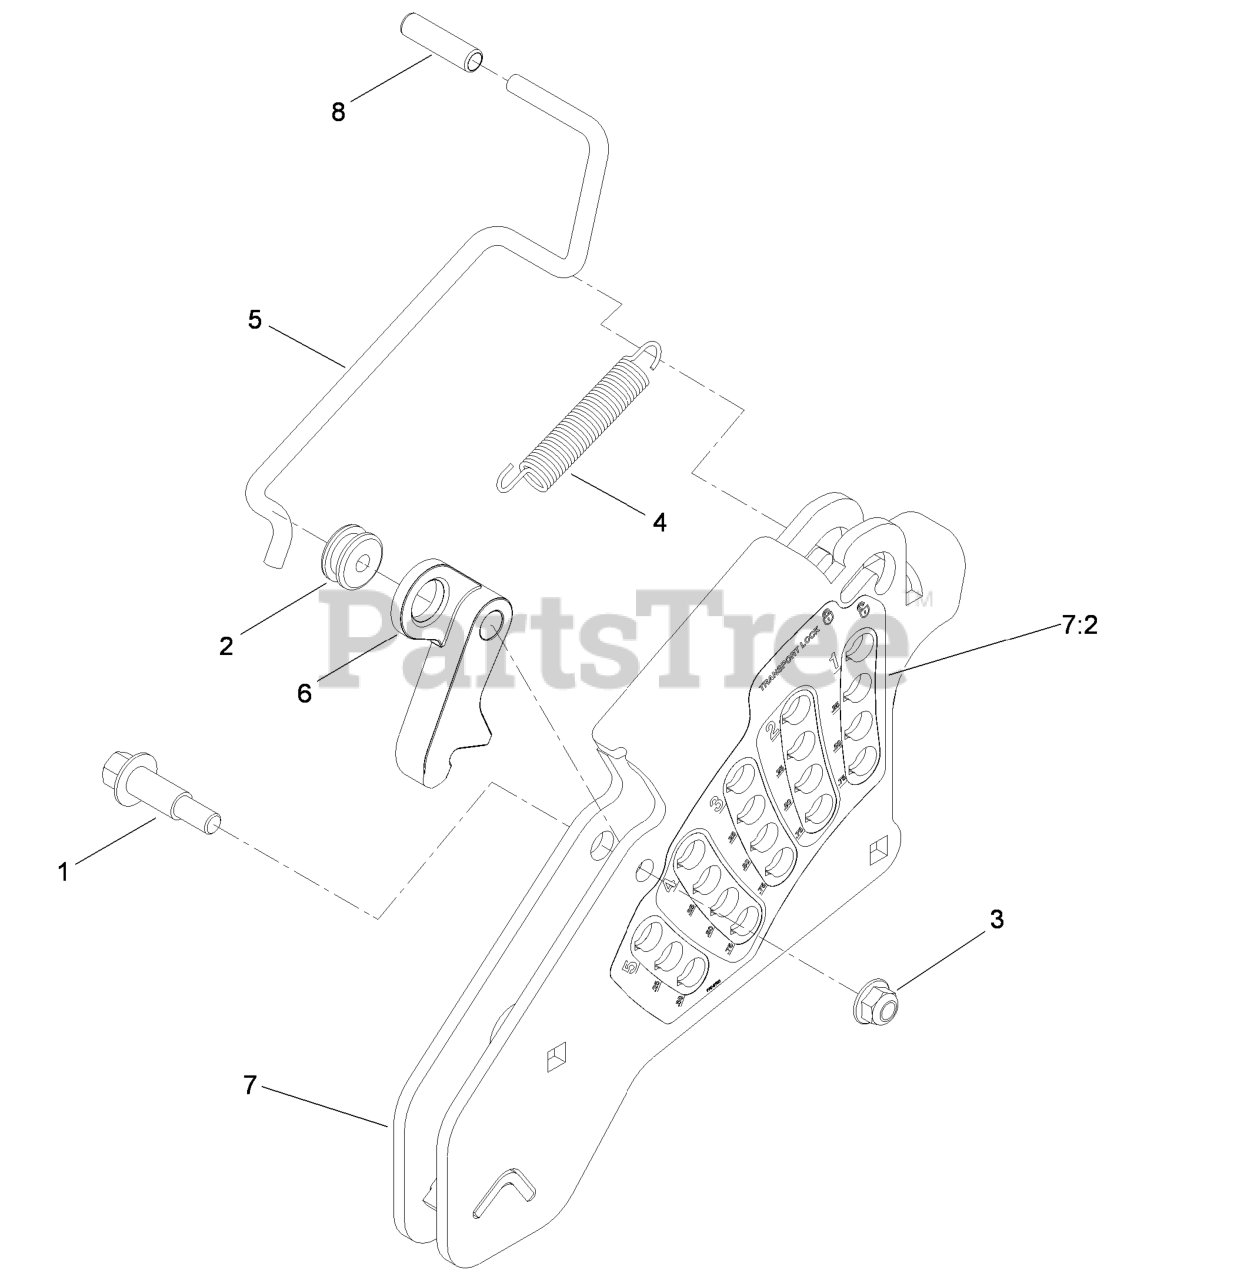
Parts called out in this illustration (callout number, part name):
1	BOLT-SHOULDER
2	GROMMET
3	NUT-HF, NI
4	SPRING-EXTENSION
5	ROD-LOCK, TRANSPORT
6	PAWL-TRANSPORT, HOC
7	HOC PLATE ASM
7:2	DECAL-HOC
8	GRIP-LEVER
